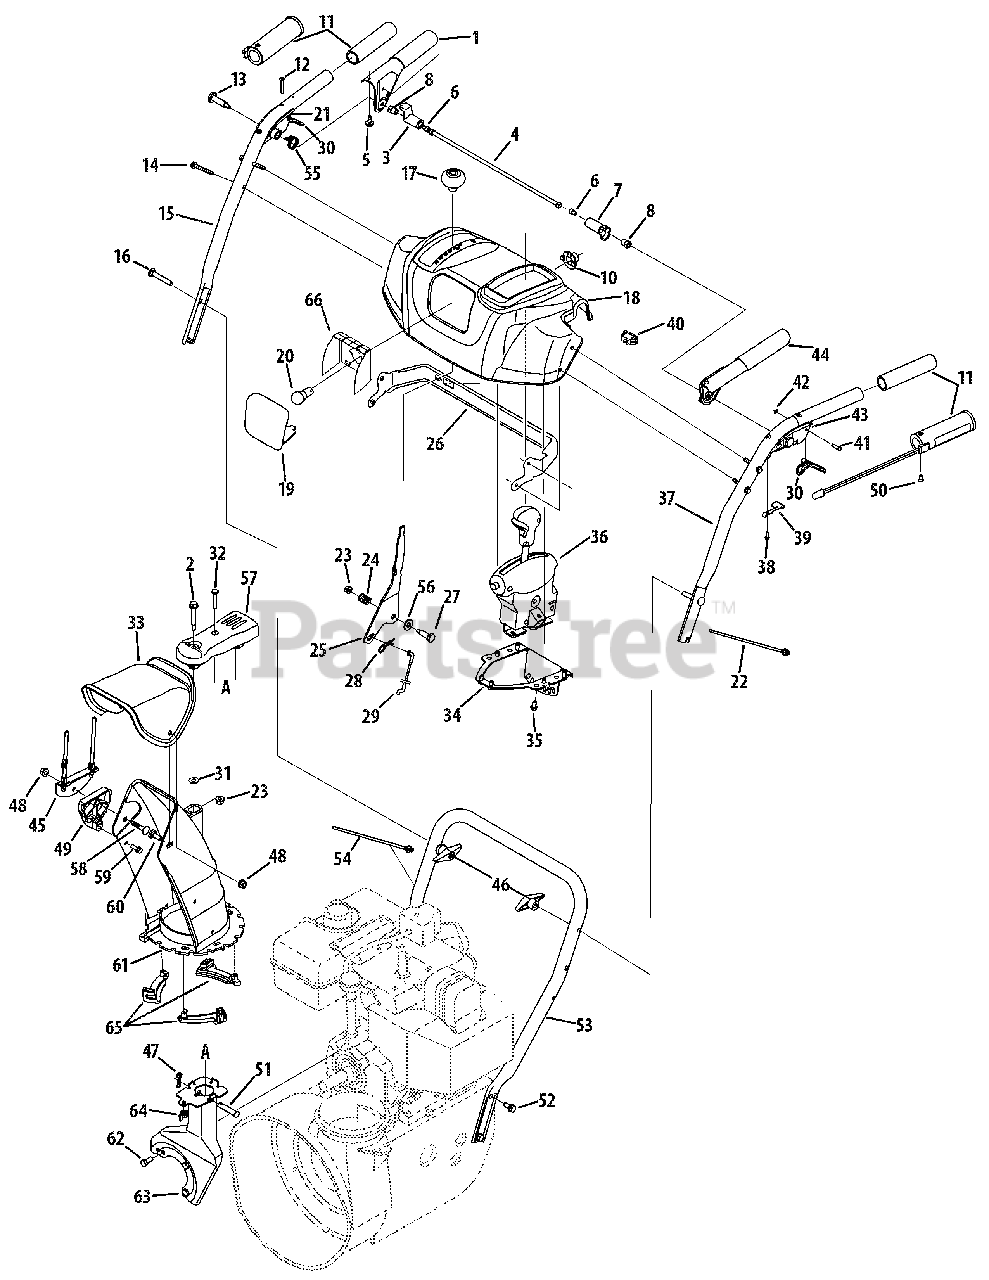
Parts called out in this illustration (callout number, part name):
1	Handle Engagement Assembly RH
2	Flange Shoulder Screw
3	Lock Plate
4	Pivot Rod
5	Rubber Bumper
6	Screw,1/4-20 x .375
7	Clutch Lock Cam
8	Shoulder Nut, 1/4-20
10	Light Socket
11	Heated Handle Grip
12	Screw, #10-24 x 0.375
13	Shoulder Screw, 1/4-20 x 1.345
14	Screw, 1/4-20 x 1.625
16	Carriage Screw, 5/16-18 x 2.25
18	Handle Panel L-Style
20	Lamp
21	Handle Clutch Lock -RH
23	Flange Lock Nut, 1/4-20
24	Compression Spring
27	Shoulder Screw
29	Speed Selector Cable
30	Steering Triggers
31	Flat Washer, .25 x .630 x .0515
32	Hex Screw, 1/4-20 x 1.50
33	Upper Chute
35	Hi-Lo Screw, 1/4-15 x 0.5
36	4-Way Chute Control
38	Screw, #8-16 x 0.50
39	Clutch Lock Spring
40	Heated Grip Switch
43	Handle Clutch Lock - LH
44	Handle Engagement Assembly LH
47	Bow-Tie Cotter Pin
48	Flange Lock Nut, 5/16-18
49	Chute Tilt Cable Guide
52	AB Screw, 5/16-18 x 0.750
55	Torsion Spring
56	Flat Washer, .385 x .87 x .06
57	JoyStick Pulley Cover
58	Carriage Bolt, 5/16-18 x 1.0
59	Hi-Lo Screw, 1/4-15 x .75
60	Carriage Bolt, 5/16-18 x 1.0
62	Hex Screw, 5/16-18 x 1.0
65	Chute Flange Keeper
66	Lens Refector Label
